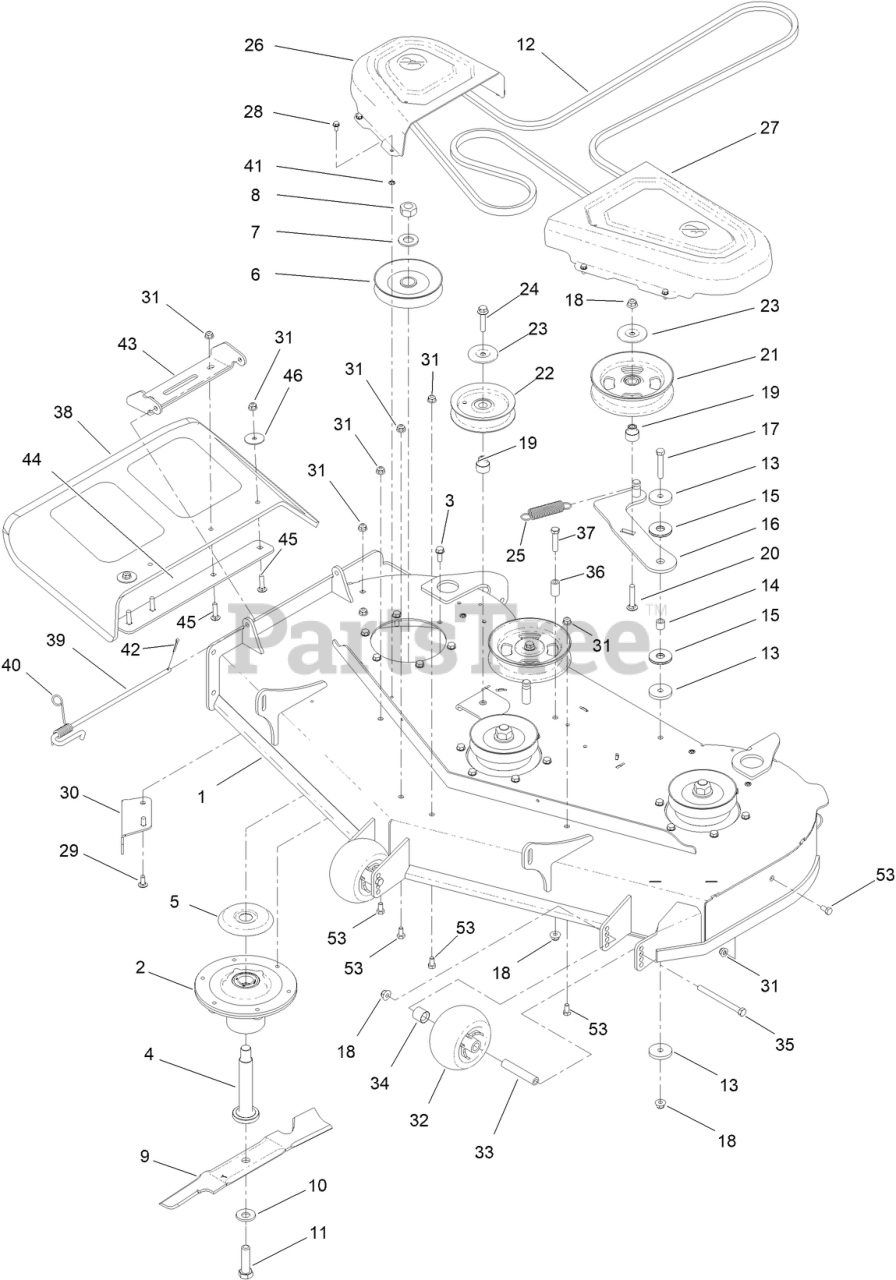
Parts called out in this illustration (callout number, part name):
1	DECK ASM-48"
2	SPINDLE ASM
3	SCREW-TAPTITE
4	SHAFT-SPINDLE
5	SHIELD-BEARING
6	PULLEY
7	WASHER
8	NUT-HEX
9	BLADE - HI FLOW, 16.50 IN
10	WASHER-BELLEVILLE
11	SCREW-BLADE
12	BELT, DECK
13	WASHER-PLAIN
14	BUSHING-IDLER
15	WASHER-FRICTION, COMPOSITE
16	IDLER ARM ASM
17	SCREW-HH
18	NUT-HF, NI
19	BUSHING-IDLER
20	SCREW-CARR
21	PULLEY-IDLER, FLAT
22	PULLEY-IDLER, FLAT
23	SHIELD-DUST
24	SCREW-HHF
25	SPRING-EXTENSION
26	COVER-BELT, RH
27	COVER-BELT, LH
28	SCREW-HWH
29	SCREW-CARR
30	BAFFLE-CUTOFF
31	NUT-HF, NI
32	ROLLER-SCALP, ANTI
33	TUBE-SPANNER
34	SPACER-AXLE, REAR
35	SCREW-HH
36	SPACER-FENDER
37	SCREW-HH
38	DEFLECTOR
39	PIN-CHUTE
40	SPRING-TORSION
41	NUT-RETAINING
42	PIN-COTTER
43	BRACKET UPPER, DEFLECTOR
44	PLATE-DEFLECTOR
45	SCREW-CARR
46	WASHER-FLAT
53	SCREW-HH
